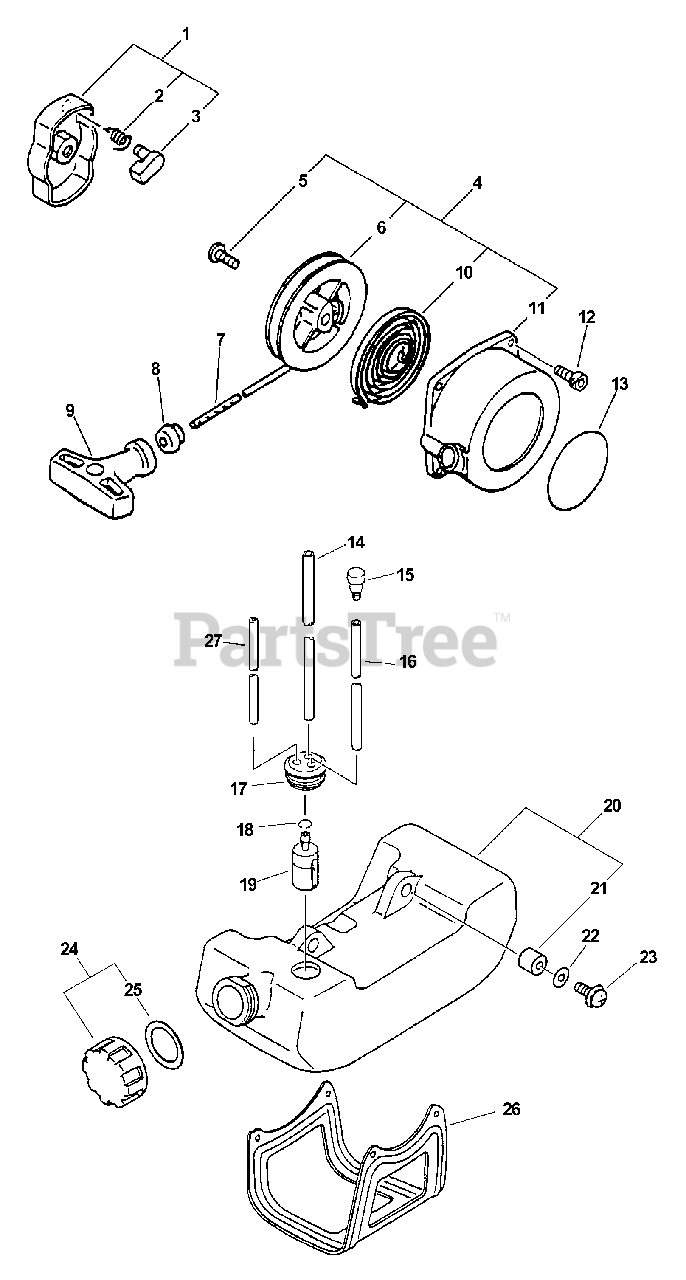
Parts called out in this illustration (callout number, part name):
1	STARTER PAWL ASSY
2	SPRING, RETURN
3	PAWL, STARTER - BLACK
4	STARTER ASSY
6	REEL, ROPE
7	ROPE, STARTER - 3X1000
8	GUIDE, ROPE
9	GRIP, STARTER
10	SPRING, REWIND
11	CASE, STARTER
12	SCREW - 4X16
13	LABEL - ECHO
14	PIPE - 3X5X180 -- BLACK
15	VENT, FUEL TANK
16	PIPE - 3X5X70 -- BLACK
17	GROMMET
18	CLIP - 6
19	FILTER, FUEL
20	TANK, FUEL
22	WASHER - 5
23	SCREW - 5X16
24	CAP ASSY
25	GASKET, CAP
26	GUARD, FUEL TANK
27	PIPE - 3X6X90 -- CLEAR
